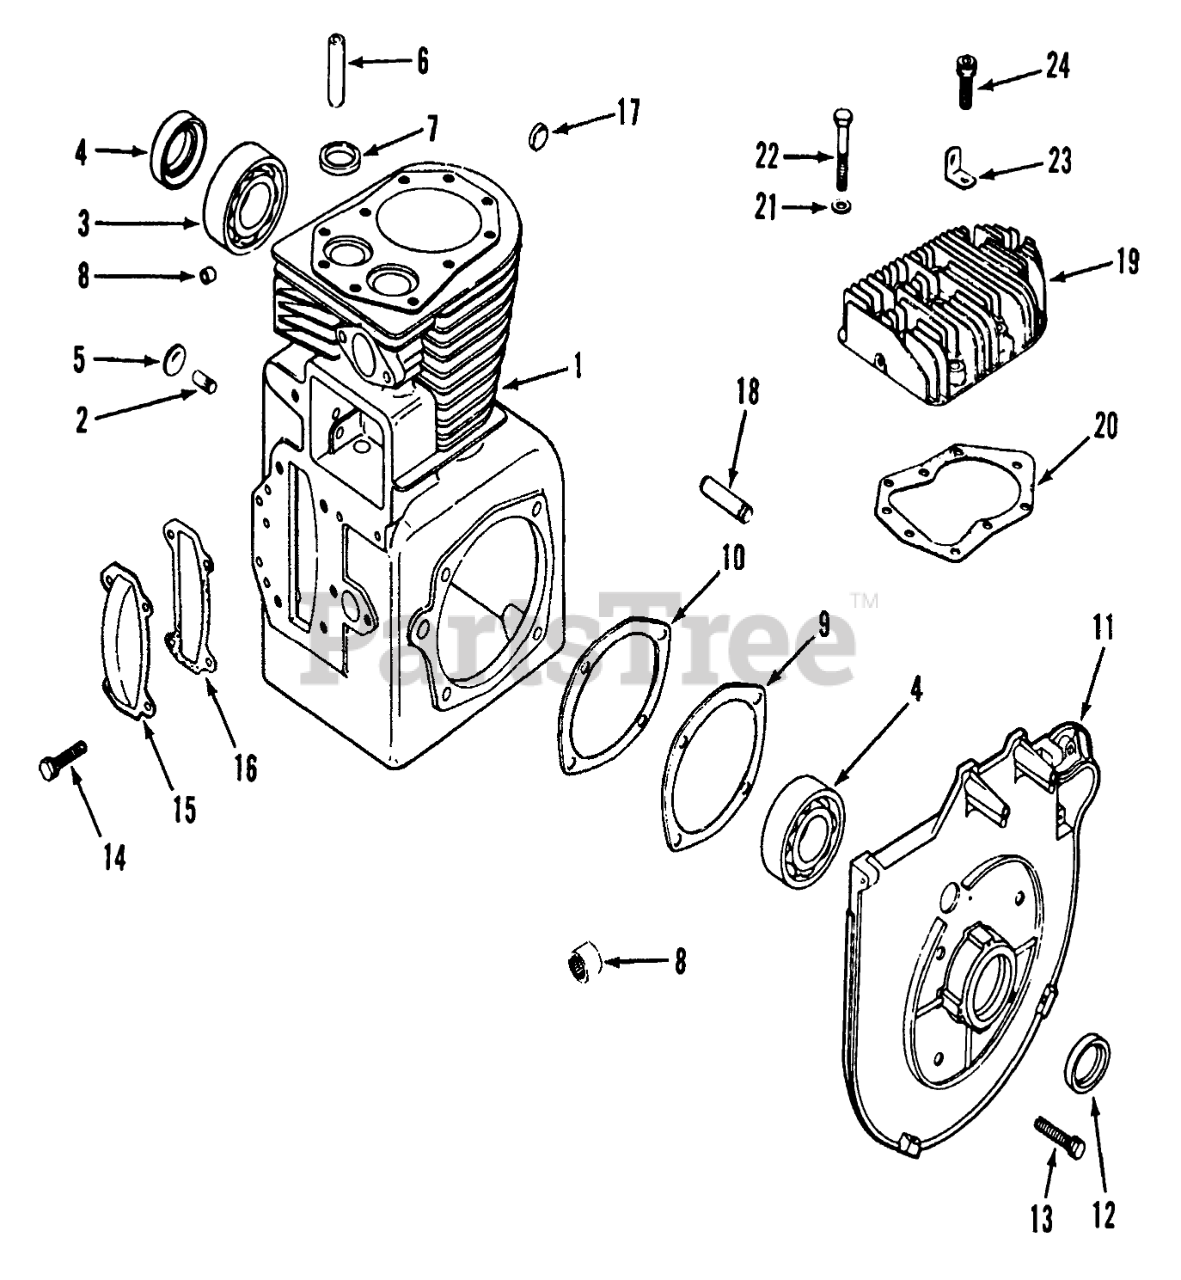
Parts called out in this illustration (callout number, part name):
1	Cylinder Bock-Service With Short Block (Includes Crankshaft)
1	KOHLER 47-522-94
1	KOHLER 77-522-35
1	Miniblock (Less Crankshaft)
1	KOHLER 47-782-32
1	KOHLER 47-782-67
1	KOHLER 47-782-34
2	KOHLER 235125-5
3	KOHLER 235376
4	KOHLER 47-032-07
5	KOHLER X-230-11
6	KOHLER 230007-5
7	KOHLER 230170
7	KOHLER 230265
8	KOHLER 234866
9	KOHLER 47-041-09
10	KOHLER 47-522-05
11	KOHLER 47-146-11
12	KOHLER 47-032-06
13	KOHLER X-159-2
14	KOHLER X-132-6
15	KOHLER 235026
16	KOHLER 235025
17	KOHLER X-702-12
18	KOHLER 236559
19	KOHLER 47-015-06
20	KOHLER 47-041-15
21	KOHLER 270889
22	KOHLER 270158
23	KOHLER 47-455-02
24	KOHLER 47-086-17
